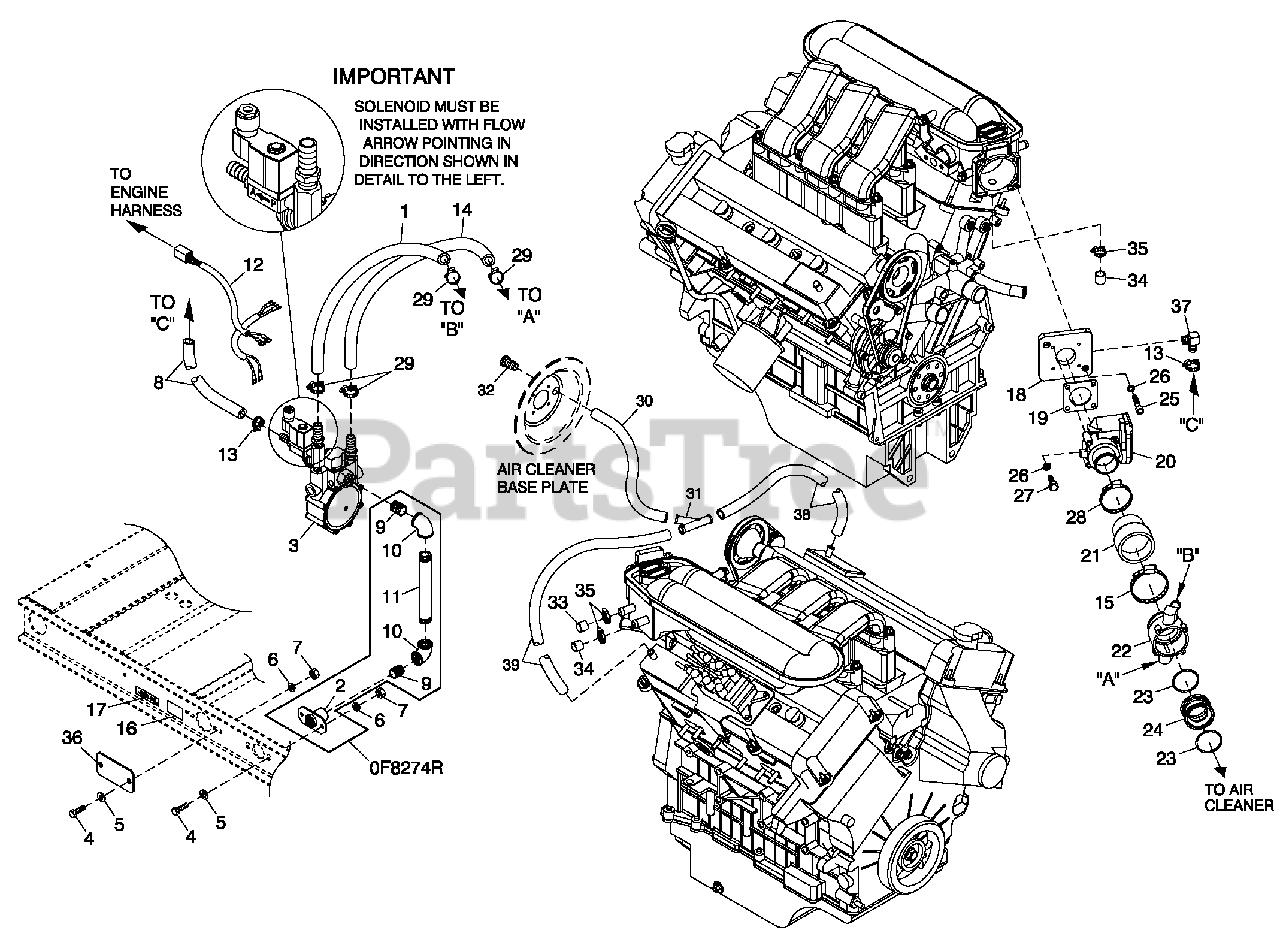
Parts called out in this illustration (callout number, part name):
1	HOSE 3/4 ID SAE-30R2 (24"LG)
2	FLANGE FUEL INLET
3	ASSY REGULATR 60KW NG
4	SCREW HHC M8-1.25 X 20 G8.8
5	WASHER FLAT 5/16 ZINC
6	WASHER LOCK M8-5/16
7	NUT HEX M8-1.25 G8 CLEAR ZINC
8	HOSE 3/8 ID SINGLE BRAID (18" LG)
9	NIPPLE CLOSE 3/4 X 1.375
10	ELBOW 90D 1-1/4 NPT
11	NIPPLE PIPE 1.25 NPT X 5.5 BL IRN
12	HARNESS FUEL JUMPER DUAL REG
13	CLAMP HOSE #8 .53-1.00
14	HOSE 3/4 ID SAE-30R2 (27" LG)
15	CLAMP HOSE #44 2.31-3.25
16	DECAL INLET PRESSURE
17	DECAL FUEL INLET NG
18	INTAKE ADAPTER BOSCH
19	GASKET BOSCH 32
20	ACTUATOR BOSCH 40 GOVERNOR
21	REDUCER RUBBER 3.0"-2.00"
22	MIXER 40/60MM ACTUATOR ASSY
23	O-RING 2-3/4 X 3/32 X 2-15/16
24	VENTURI THROTTLE 32MM
25	SCREW SHC M6-1.0 X 25 G12.9 ZP
26	WASHER LOCK M6-1/4
27	SCREW HHC M6-1.0 X 50 G8.8
28	CLAMP HOSE #36 1.88-2.75
29	CLAMP HOSE #10 .56-1.06
30	HOSE 5/8" ID 250#WP (18.5" LG)
31	BARBED Y 5/8-HOSE
32	ADAPTER INSERT HOSE BARB 5/8"
33	CAP VINYL .5" ID X 1.0" DP BLK
34	CAP VINYL 3/8" ID X 1" DP BLK
35	CLAMP HOSE .38-.87
36	COVER FUEL INLET LP
37	NIPPLE CLOSE 1.25 NPT X 1.625
38	PIPE TEE 1-1/4 NPT
39	BSHG RDCR HEX 1-1/4-3/4
40	WASHER FLAT 3/8 ZINC
41	BARBED EL 90 1/4NPT X 3/8
42	HOSE COOL 5/8"ID 250#WP (11"LG)
43	HOSE COOL 5/8"ID 250#WP (14.5"LG)
